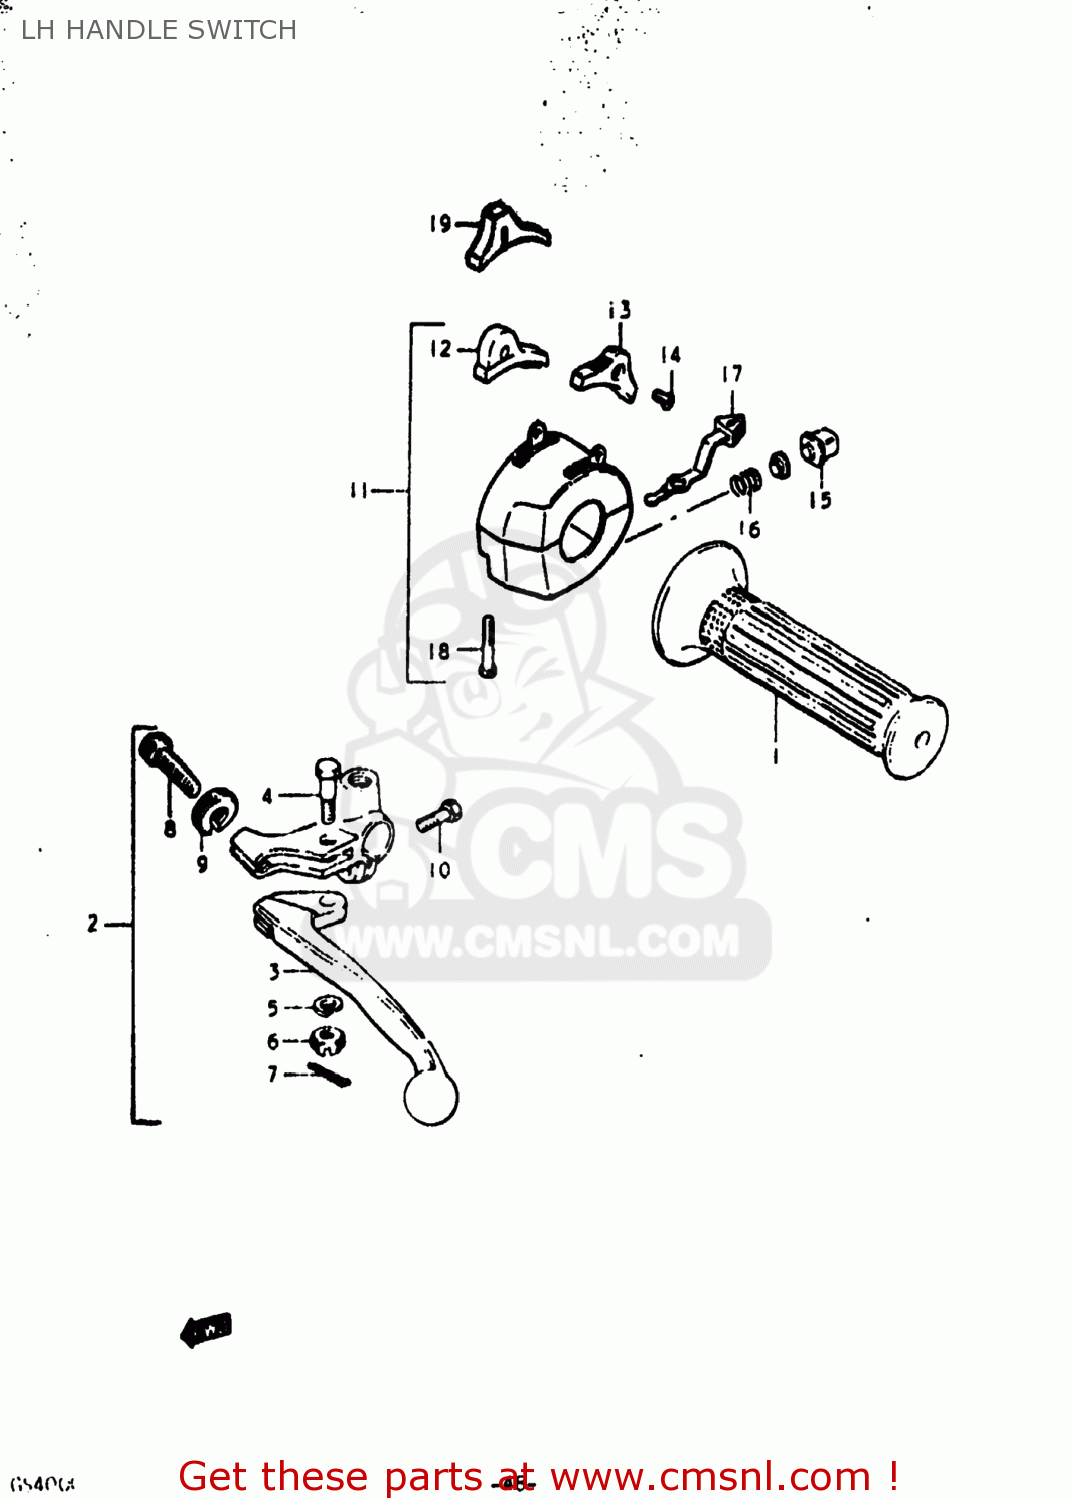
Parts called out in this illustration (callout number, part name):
1	GRIP,L
2	LEVER ASSEMBLY
3	LEVER,CLUTCH
4	BOLT,LEVER
5	LOCK WASHER
6	NUT,LEVER FITTNG
7	COTTER PIN
8	ADJUSTER,CABLE
9	NUT,CABLE ADJUSTER
10	BOLT
11	SWITCH ASSEMBLY,HANDLE,LEFT
12	KNOB,STOP SWITCH
13	KNOB,DIMMER SWITCH
14	SCREW
15	BUTTON,HORN
16	SPRING
17	KNOB,TURNSIGNAL
18	SCREW
19	KNOB,LIGHTING SWITCH
